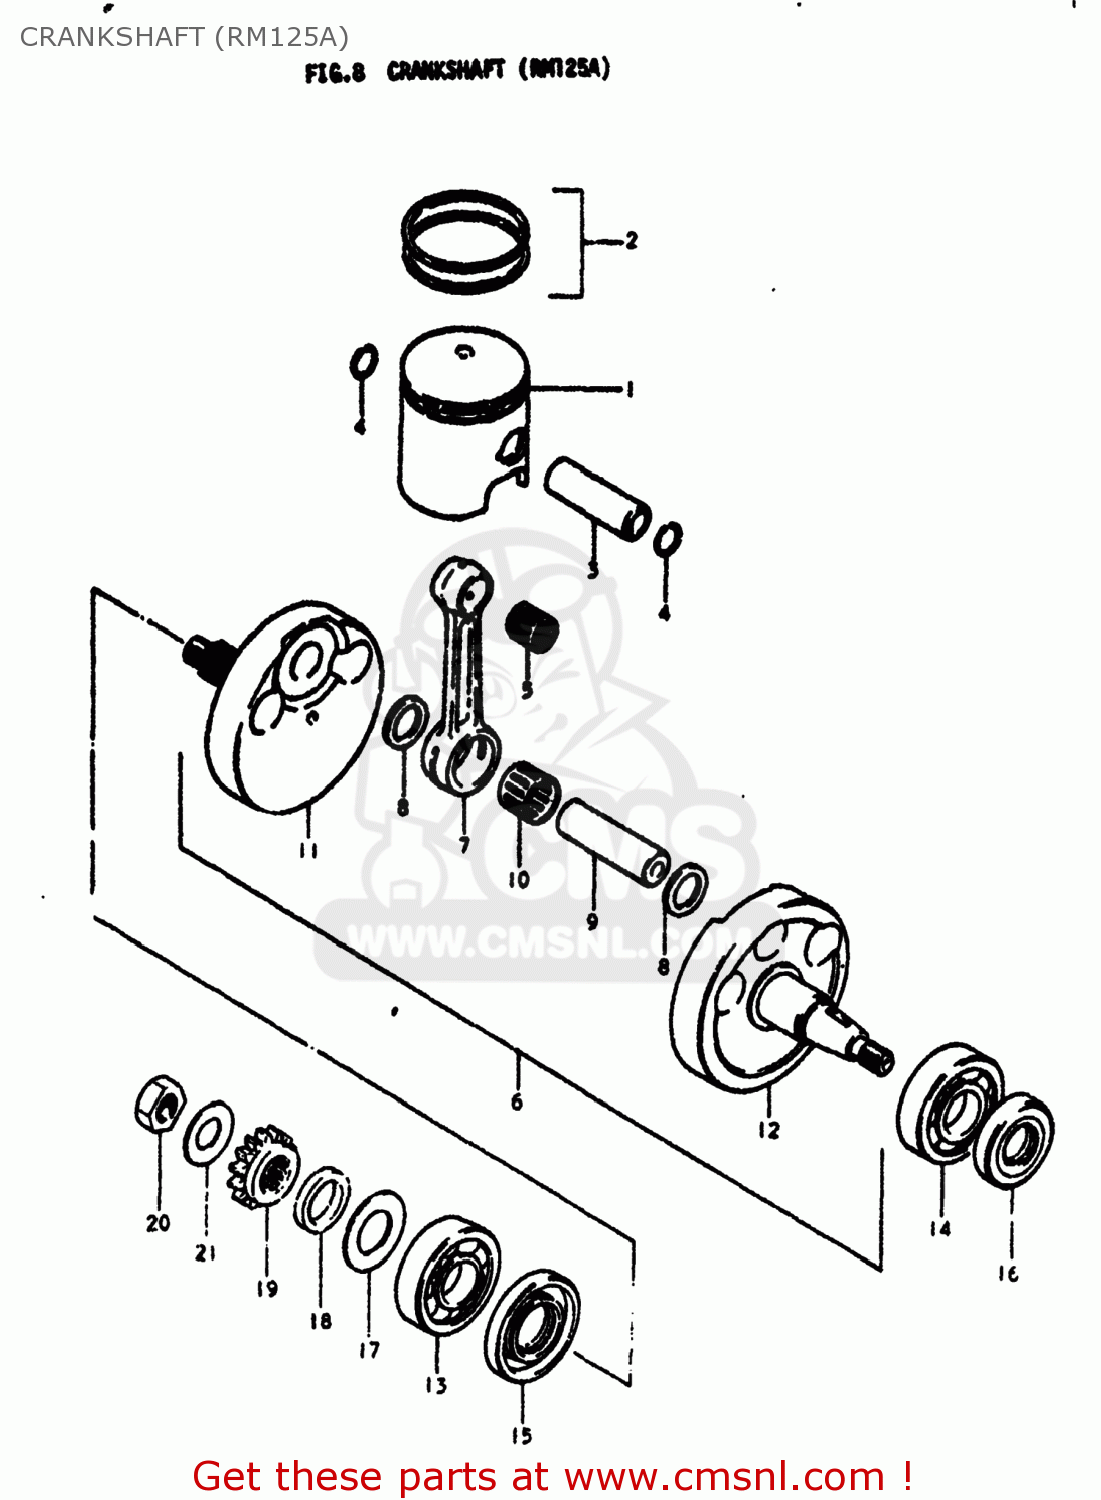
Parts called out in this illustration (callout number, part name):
1	PISTON
2	RING SET,PISTON
3	PIN,PISTON 16MM
4	RING,SNAP 16MM
5	BEARING
6	CRANKSHAFT ASSEMBLY
7	ROD,CONNECTING
8	WASHER(19X32X1)
9	PIN,CRANK
10	BEARING
11	CRANKSHAFT
12	CRANKSHAFT,LEFT
13	BEARING
14	BEARING
15	SEAL,OIL(30X56X9)
16	OIL SEAL
18	SPACER
19	GEAR,PRIMARY DRIVE
20	NUT
21	WASHER
